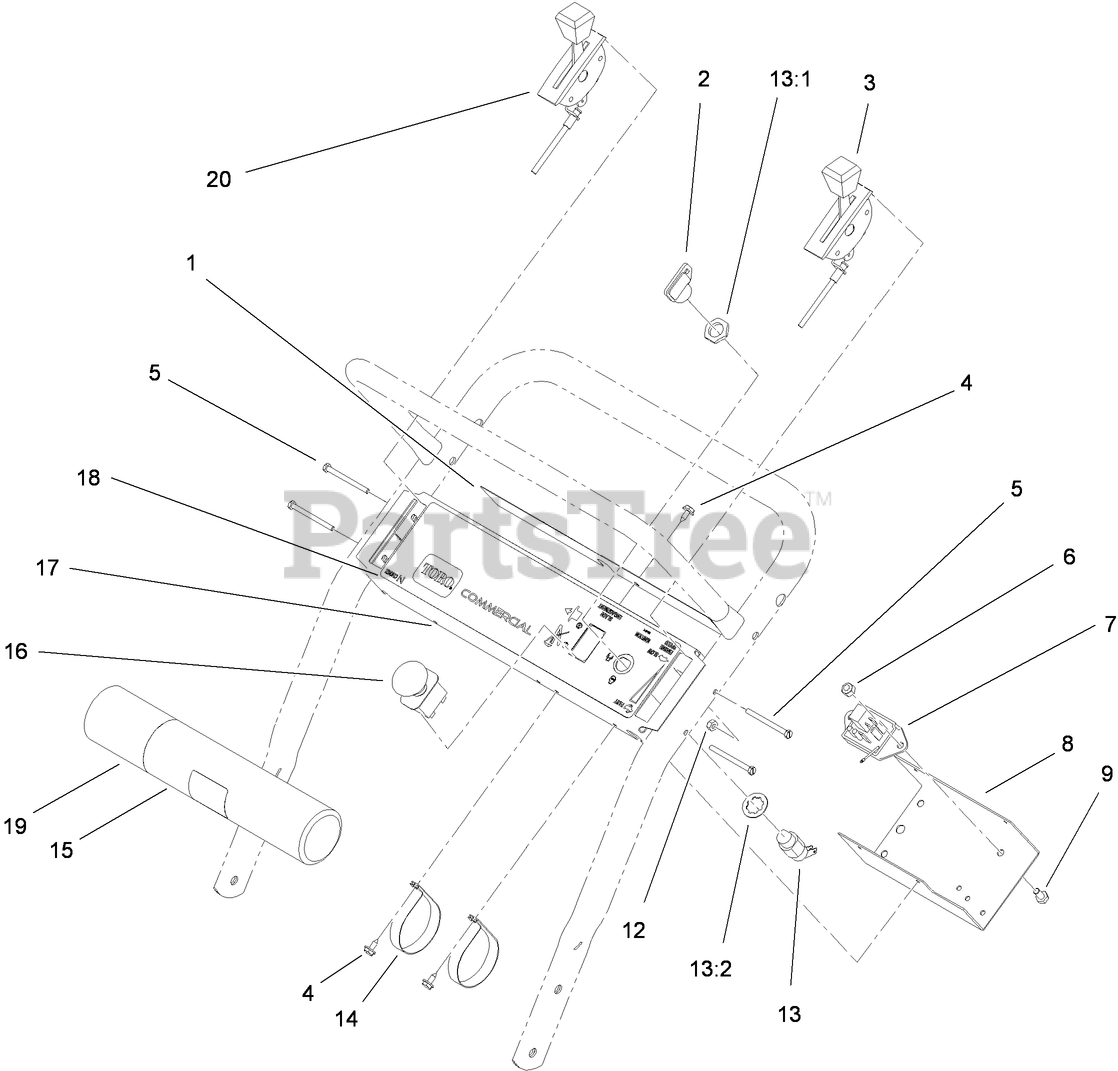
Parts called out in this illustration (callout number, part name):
1	DECAL-DANGER
2	KEY-IGNITION
3	CABLE-THROTTLE
4	SCREW-HWHTF
5	SCREW-SHH
6	NUT-LOCK, NI
7	MODULE-DELAY
8	PANEL-BOTTOM
9	SCREW-HH
12	NUT-LOCK, NI
13	SWITCH-ON / OFF
13:1	NUT-HH
13:2	WASHER-TOOTH, INTERNAL
14	CLAMP-R
15	TUBE-MANUAL
16	SWITCH-PTO
17	PANEL-CONTROL
18	DECAL-PANEL, CONTROL
19	CAP-HOUSING
20	CABLE-CHOKE
